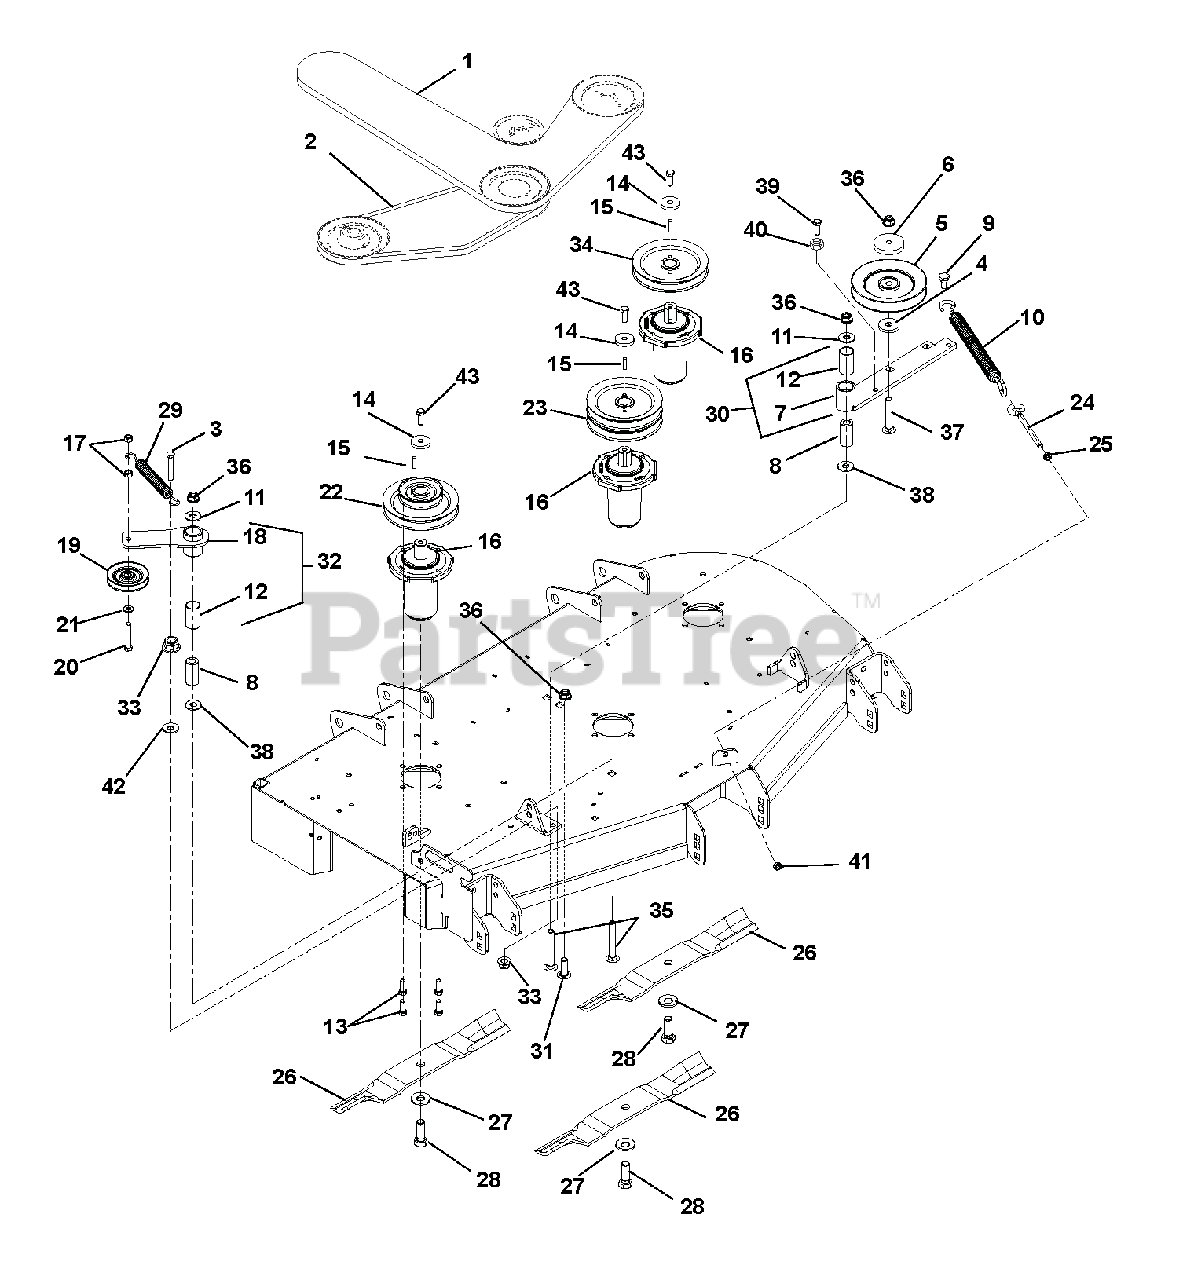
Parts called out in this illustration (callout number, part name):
1	HEX BELT, BB-WRAPPED
2	V-BELT, B-COGGED
3	@BLT-HEX .38-16X3.00 GR5 YWZC
4	BSHG, SPCR .502X.997X.50 PM
5	SHV, .50"ID X 6.00"OD V-IDLER
6	CAP, IDLER BEARING SEALING
7	WMT, IDLER ARM
8	BSHG, SPCR .502X.997X2.03 PM
9	BLT,SHLDR EP .38-16X.30 HEX YZ
10	SPRING, EXTENSION
11	@WSHR-FL-STL.563X1.38X.109YWZC
12	BSHG, 1.00 X 1.125 X 1.937
13	BLT-HEX .38-16X1.0 GR8 YZ EP30
14	RETAINER, SHEAVE
15	KEY, SQ .25X.25X1.00 RC 40-50
16	ASM, MAINT FREE SPINDLE
17	@NUT-LK-CTR .38-16 YWZC
18	WMT, IDLER ARM
19	IDLER, V-5.00"
20	@BLT-HEX .38-16X2.25 GR5 YWZC
21	@WSHR-FL-STL.406X.812X.065 YWZ
22	PULLEY, DBL-1"IDX5.75"&3.50"OD
23	PULLEY, DOUBLE-1"ID X 5.75"OD
24	BOLT, .38-16X4.50 .62 DIA EYE
25	NUT-HEX-JAM .375-16 YWZC
26	BLADE, 16.19" MOWER (HI-LIFT)
27	WSHR-BLVL .669X1.535X.138
28	BLT-HEX .62-18X1.75 GR8 YWZC
29	SPRING, EXTENSION
30	ASM, IDLER PIVOT ARM (PTO)
31	BLT-RDHDSHSQNKFT.50-13X1.50 G5
32	ASM, IDLER ARM (DECK)
33	@NUT-SPNLK-FLG .375-16 YWZC
34	PULLEY, V-1" ID X 5.75" OD
35	@BLT-RDHDSQNK .50-13X3.50 G5YZ
36	@NUT-LK-NYL-FLG .50-13 YWZC
37	@BLT-RDHDSQNK .50-13X3.00 G5YZ
38	WSHR-FLT .640X1.75X.250
39	@BLT-HEX .38-16X2.75 GR5 YWZC
40	@NUT-HEX .38-16 YWZC
41	@NUT-LK-CTR-JAM .375-16 YWZC
42	WSHR-FL-STL .406X1.375X.135 YZ
43	BLT-HEX .38-16X2.75 GR8 YWZC
